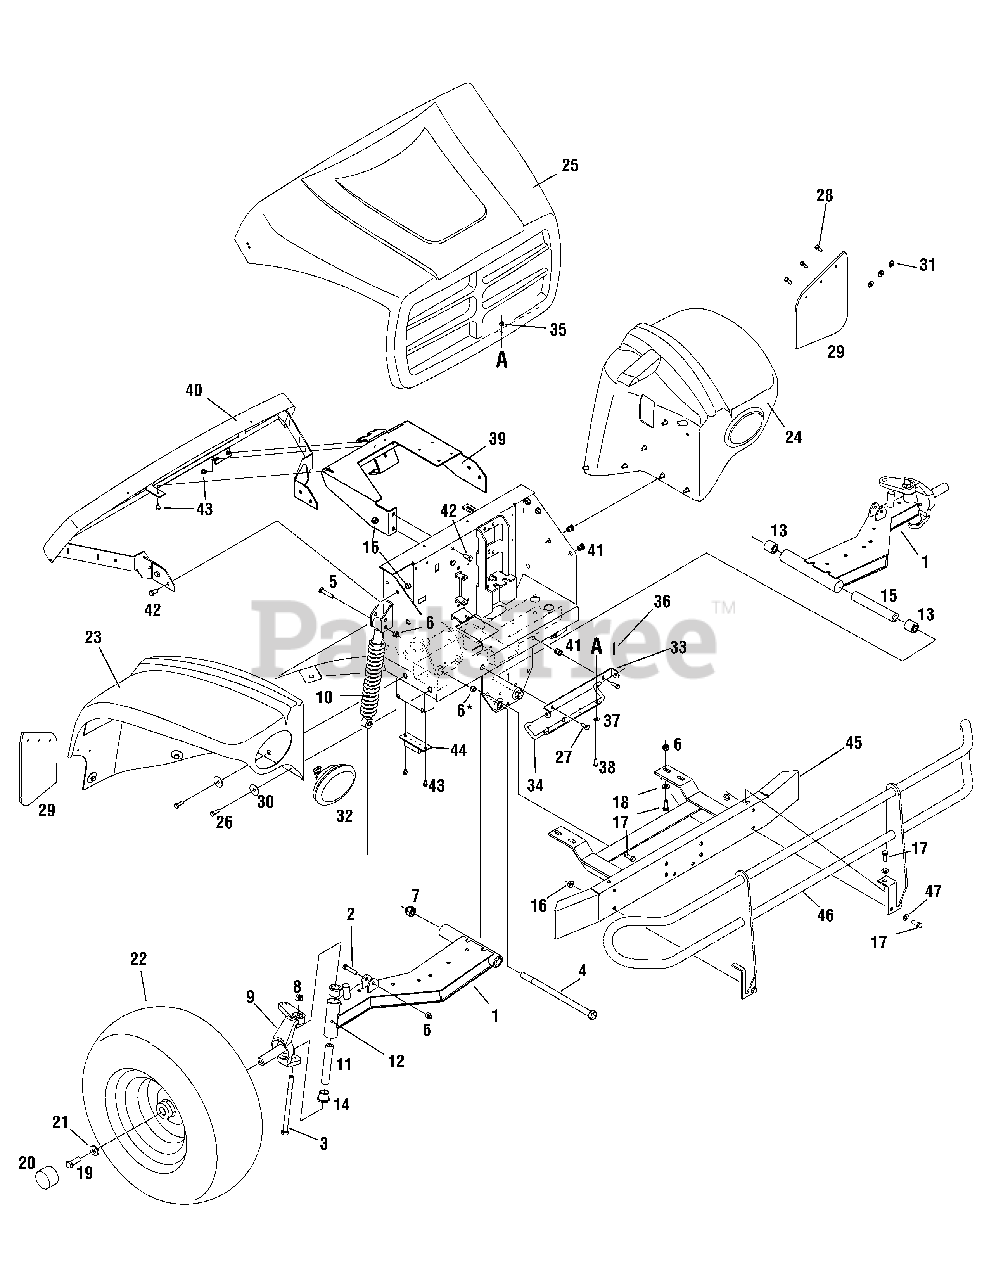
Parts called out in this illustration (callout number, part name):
1	Axle Assembly, Right-front (Incl. Ref 12-15)
1	Axle Assembly, Left-front (Incl. Ref 12-15)
2	Hex Screw, 3/8-16 x 1.75
3	Hex Screw, 1/2-13 x 7.0, Gr5
4	Hex Screw, 5/8-11 x 11.13, Gr5
5	Hex Screw, 3/8-16 x 2.25
6	Nut, Hex Lock, Nylon, 3/8-16, Gr5
7	Nut, Hex Lock, Nylon, 5/8-11, Gr5
8	Nut, Hex Lock, 1/2-13
9	Steering Control Knuckle, RH
9	Steering Control Knuckle, LH
10	Shock Absorber, 2.9 Stroke
11	Tube, .875 x .50 x 4.75
12	Grease Fitting
13	Bearing, .63 ID x 1.19 OD
14	Bushing, Steering
15	Spacer, .645 ID x 1.063 OD
16	Flange Lock Nut, 3/8-16
17	Hex Screw, 3/8-16 x 1.0
18	Flat Washer,.406 x.875 x.059
19	Hex Screw, 1/2-13 x 1.25, Gr5
21	Flat Washer,.531 x 1.25 x.181
22	Tire 23 x 8
22	Hub
23	Panel Assembly, Right Fender, Yellow
23	Panel Assembly, Right Fender, Camo
24	Panel Assembly, Left Fender, Yellow
24	Panel Assembly, Left Fender, Camo
25	Panel Assembly, Hood, Yellow
25	Panel Assembly, Hood, Camo
26	Hex Screw 5/16-18 x 1.00 Gr 5
27	Hex Screw, 5/16-18 x.75
28	Pop Rivet
30	Washer, Bell,.39 x 1.38 x.062
31	Flat Washer, .194 x .62 x .063
32	Head lamp Assembly
35	Nut, Hex Lock, 1/4-20
36	Cotter Pin, Internal, 1.42
37	Washer, Flat,.271 x.63 x.065
38	Hex Screw, 1/4-20 x.75
41	Insert Nut, 5/16-18
42	Hex Screw, 3/8-16 x.75
43	Screw, Self-tapping, 1/4-20 x.5
44	Suspension Bumper
47	Washer, Flat, 406 x .810 x .051
